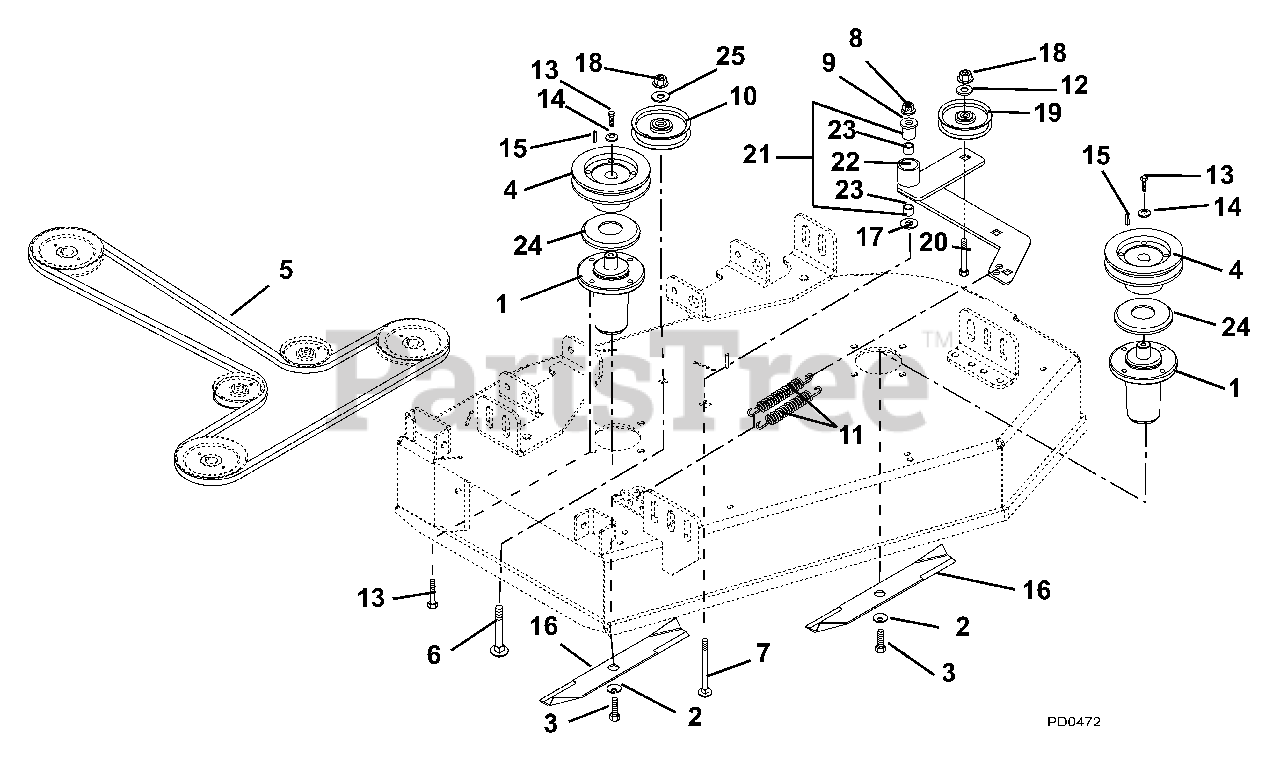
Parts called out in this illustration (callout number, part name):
1	Assembly, Maintenance Free Spindle
2	Washer-Bellville .63 x 1.625 x .14
3	Bolt-Hex .62-18 x 1.75 Grade 8
4	Sheave, 5.00 Spindle (1.00 I.D.)
5	V-Belt, B-Section 49.68 x .62548.80 x .625; Circumference aprox. 112
6	Bolt-Round Head Square Neck .38-16 x 3.0 Grade 5
7	Bolt-Round Head Square Neck .50-13 x 3.50 Grade 5
8	Nut, Nyloc Flange .50-13
9	Bearing, Pedestal
10	Idler-Flat 4.00 x .38 (2.00 W)
11	Spring, Extension
12	Washer-Flat-Steel .375 x 1.125 x .065
13	Bolt, Hex .38-16 x 1.00 EP30
14	Washer-Flat-Steel .406 x 1.50 x .245
15	Key, Square .25 x .25 x 1.00
16	Blade, Mower Hi-Lift (056)
16	Blade, Mulching 50" Mower
17	Washer, Flat Steel .531 x 1.250 x .100
18	Nut, Nyloc Flange 3/8-16
19	Idler, Flat 4.00 x .38 (1.00 W)
20	Bolt, Round Head Square Neck .38-16 x 2.00 Grade 5
21	Assembly, Idler Pivot Arm
22	Weldment, Idler Pivot Arm
23	Bearing, 1.00 x 1.12 x .75
24	Slinger, Dust
25	Seal, Idler Bearing
